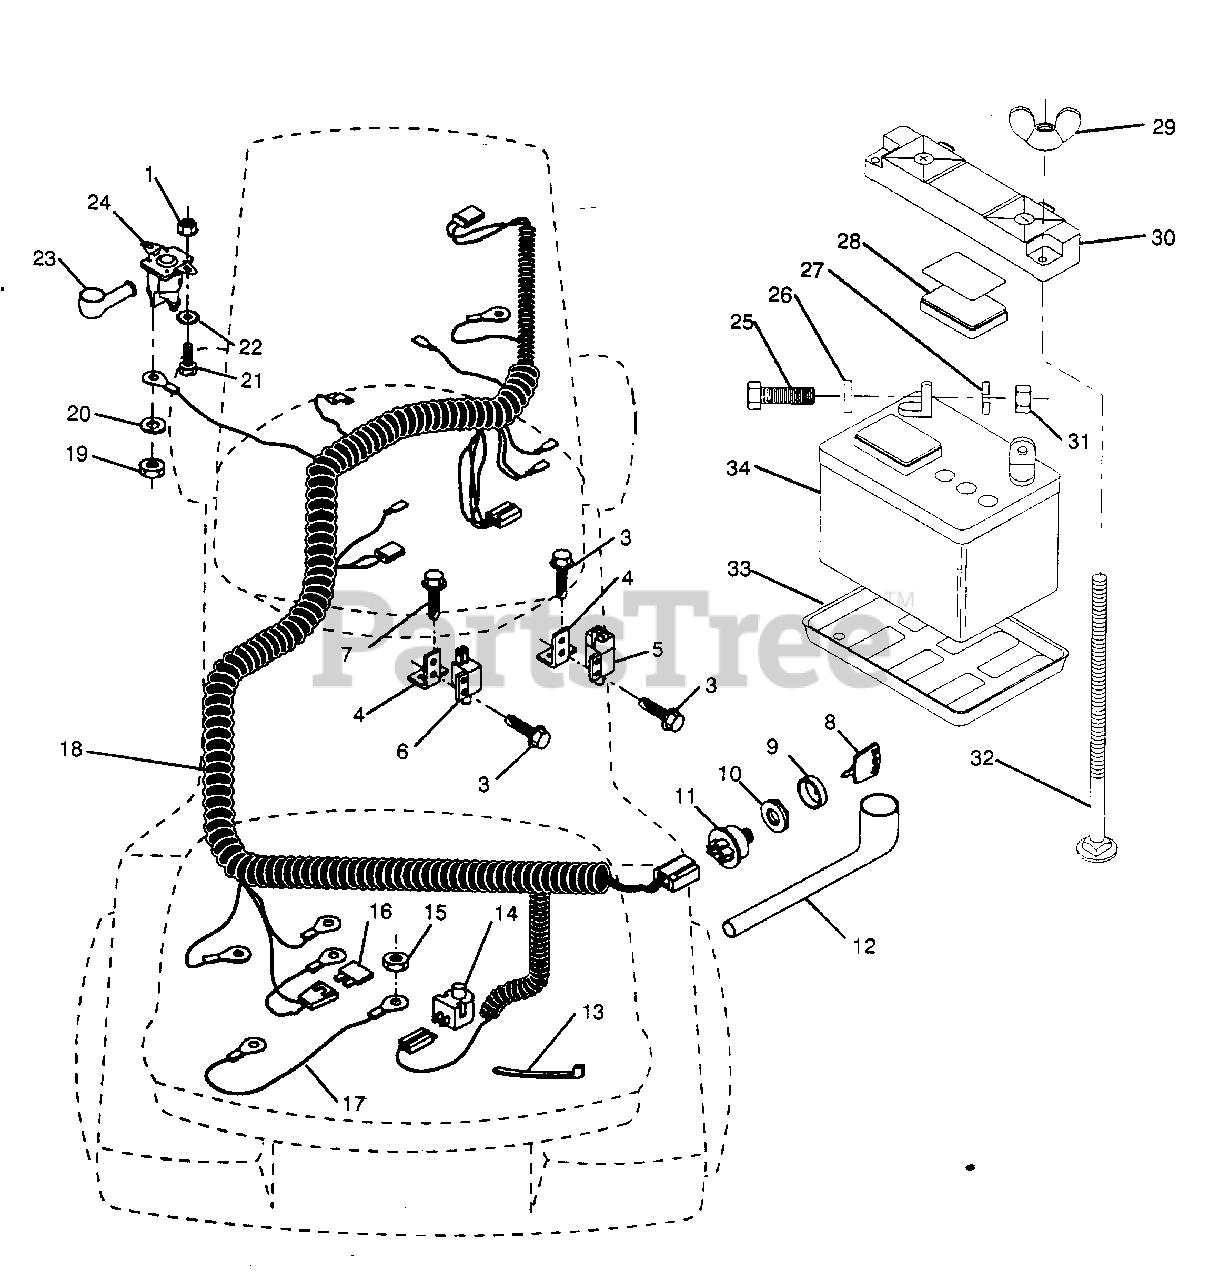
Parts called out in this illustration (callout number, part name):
1	Nut Hex Keps 1/4-20
2	Assembly, Cable
3	Screw, Tap Hex Hd #10-24 x 1/2
4	Bracket, Switch
5	Switch, Interlock
6	Switch, Interlock
7	Screw, Hex Wsh. Tap #10-16 x 1/2
9	Cover, Key Ignition
10	Nut, Ignition
11	Switch, Ignition
12	Cover, Ignition Switch
13	Tie, Cable
14	Switch, Plunger
15	Keps, Nut 5/16-18
17	Assembly, Cable
18	Harness, Ignition
19	Nut, Hex Jam 1/4-20
20	Washer, Lock 1/4
21	Bolt Fin. Hex 1/4-20 UNC x 1/2 Gr.5
22	Washer, Lock Ext. Tooth 1/4
23	Cover, Terminal
24	Solenoid
25	Bolt, Hex Hed. 1/4-20 UNC x 3/4
26	Washer 9/32 x 5/8 x 16 Ga.
27	Washer, Lock Hvy. Helical Spring 1/4
29	Nut, Plastic, Locking Nut 1/4-20
30	Guard, Terminal
31	Nut, Fin. Hex 1/4-20 UNC
32	Bolt, Carriage 1/4-20 UNC x 7 1/2
33	Tray, Battery
34	Battery
